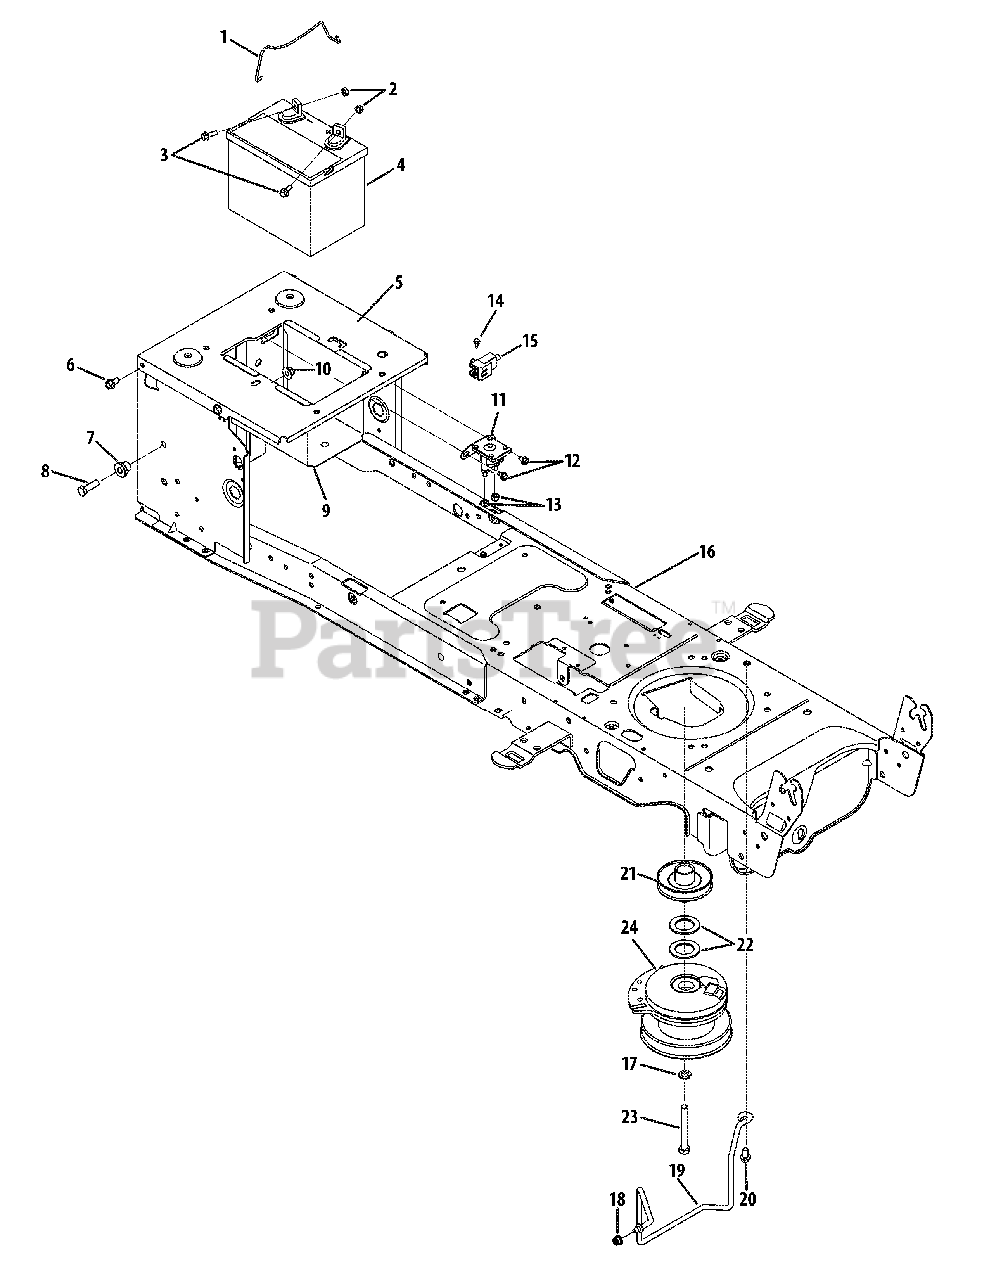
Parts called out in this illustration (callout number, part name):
1	Battery Hold-Down Rod
2	Sems Nut, 1.4-20
3	Hex Flange, 1.4-20 x .75
5	Seat Frame Bracket
6	Hex Washer Screw, 5.16-18 x .750
7	Shoulder Spacer, .38 x 1.0 x .70
8	Hex Screw, 3.8-16 x 1.25
10	Flange Lock Nut, 3.8-16
11	Solenoid
12	Hex Washer Screw, 1.4-20 x .375
13	Flange Lock Nut, 1.4-20
14	Shoulder Screw, #10-32 x .500
15	Interlock Switch
16	Lower Frame Assembly
17	Lock Washer, 7.16 (All Models)
18	Flange Lock Nut, 5.16-18 (All Models)
19	Keeper Rod
20	Hex Washer Screw, 5.16-18 x .750
21	Engine Pulley
22	Flat Washer, 1.031 x 1.620 x .095
23	Hex Screw, 7.16-20 x 3.50
24	Electric PTO Clutch - SLTX1050
